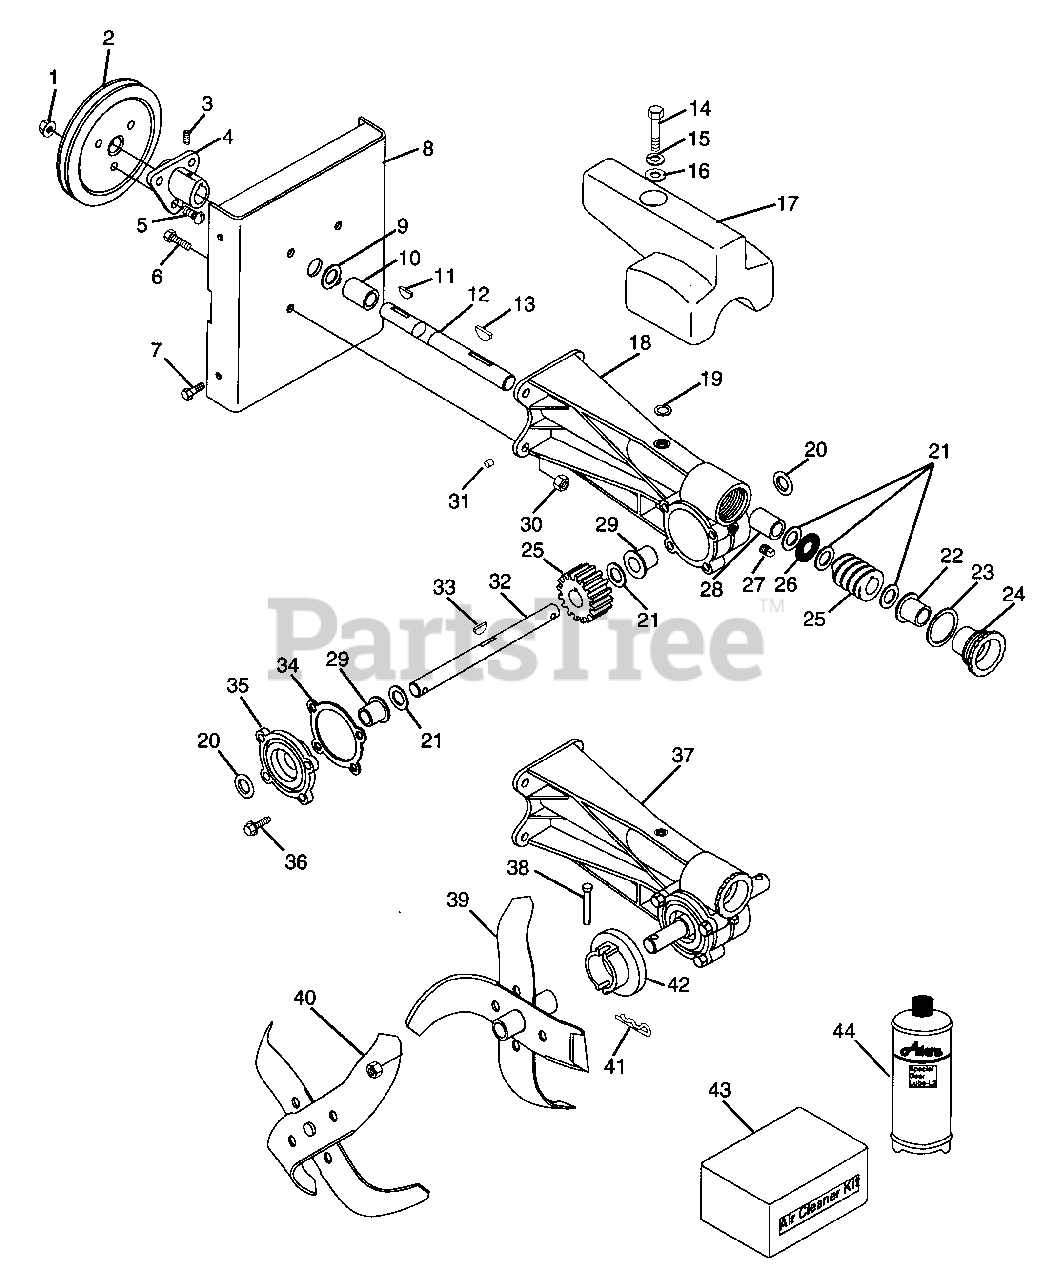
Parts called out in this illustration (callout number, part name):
1	@NUT-LK-CTR .31-18 YWZC
2	PLY-V 8.50 X 1.25 3BLT
3	SCR-SET .32-18X.38 SKHCUPNL OH
4	HUB
5	BLT-SERRDHD SL .31-18X.75 YZ
6	BLT-SERHFWH .375-16X1.0 YWZC
7	@SCR-TAP .31-18X.50 HWH TR YWZ
8	TILLER MOUNTING PLATE W/DECAL
9	SEAL .750X1.000X.125
10	BSHG-SLV .750X1.000X1.000
11	KEY-WDRF .188X.875X.375 SAE11
12	WORM SHAFT
13	KEY-FTHR .188X1.38X.188
14	@BLT-HEX .38-16X2.25 GR5 YWZC
15	@WSHR-LK .38X.094 REG YWZC
16	@WSHR-FL-STL.406X.812X.065 YWZ
17	TILLER WEIGHT
18	GEARCASE - ALUMINUM
19	SHIM SPACER
20	SEAL .750X1.980X.375
21	WSHR-HDND-THRST .755X1.40X.062
22	BSHG-FLG .750X1.000X.750X1.132
24	ADJUSTMENT PLUG
25	WORM & WORM GEAR ASSEMBLY
26	BRG-N THRST .754X1.24X.078
27	PIPE PLUG
28	BSHG-SLV .750X1.000X.750
29	BSHG-FLG .750X1.250X.750X1.375
30	@NUT-SPNLK-FLG .375-16 YWZC
31	BREATHER
32	TINE SHAFT
33	KEY-WDRF .188X.625X.25 SAE 61
36	SCR-TAP .312-18X1.0 HWH PL TR
37	TILLER GEARCASE - ALUMINUM
38	PIN, CLEVIS .243/.248X1.50 YWZ
39	R H INNER TINE SPOOL
39	L H INNER TINE SPOOL
40	R H OUTER TINE SPOOL
40	L H OUTER TINE SPOOL
41	PIN-HAIR INT .08X.18X1.18
42	DUST CAP
43	AIR CLEANER KIT
44	ARIENS 16 OZ.BOTTLE OF L2 LUBE
